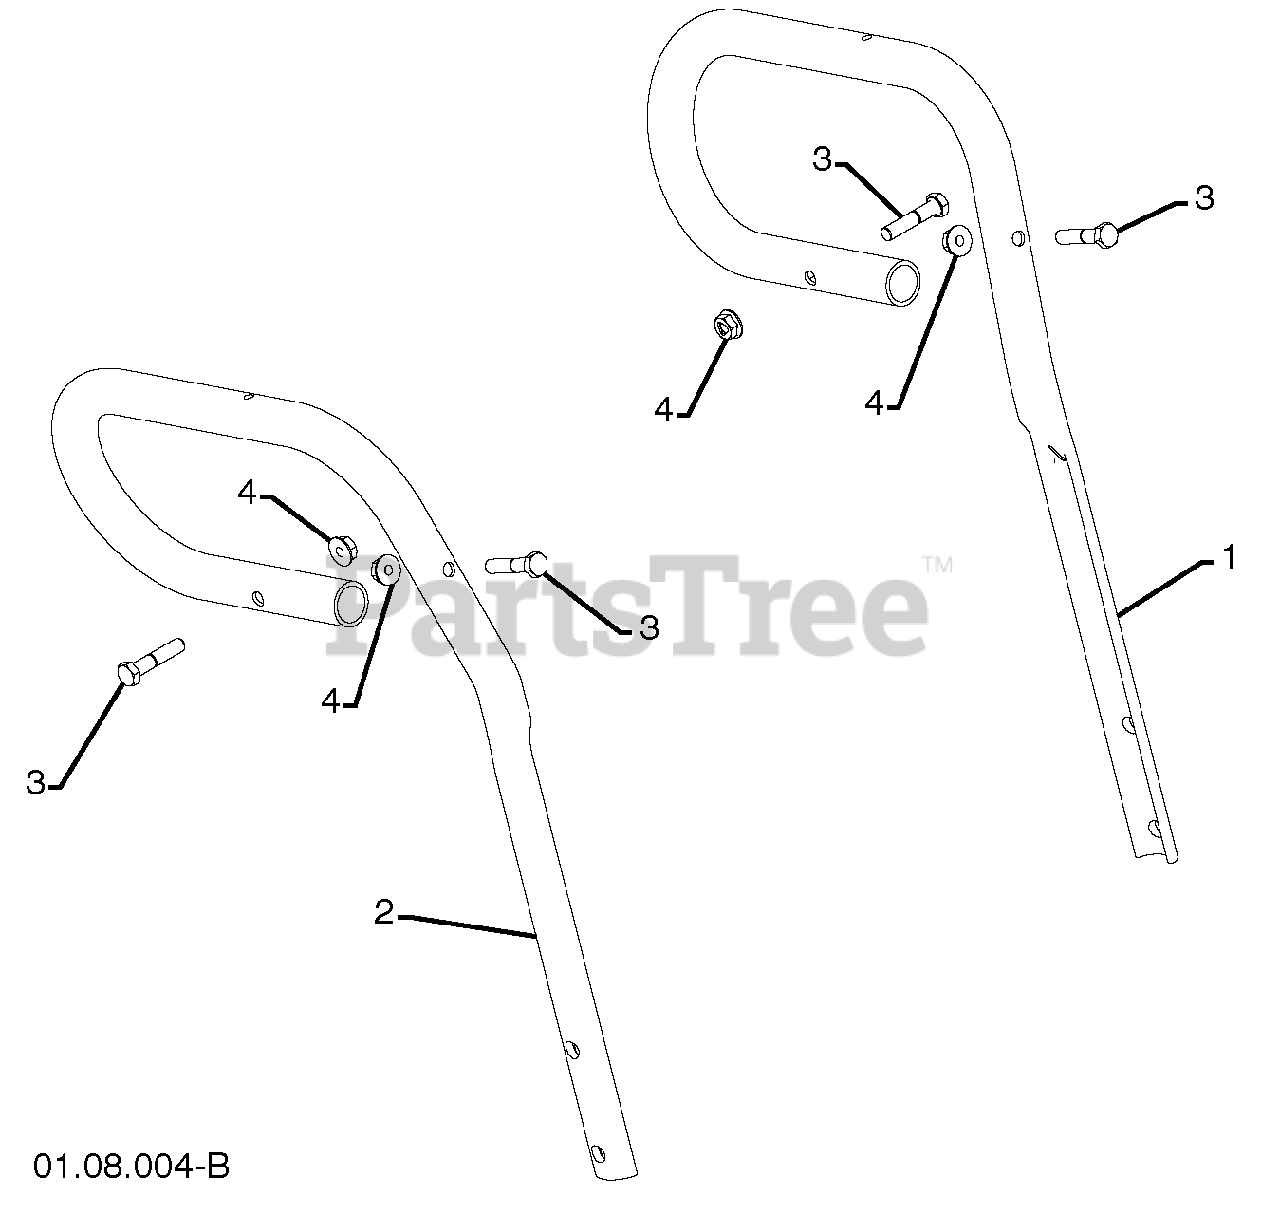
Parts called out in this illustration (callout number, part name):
1	LOOP HANDLE LH
2	LOOP HANDLE RH
3	SCREW 5/16-18 X 1.50
4	NUT 5/16-18
